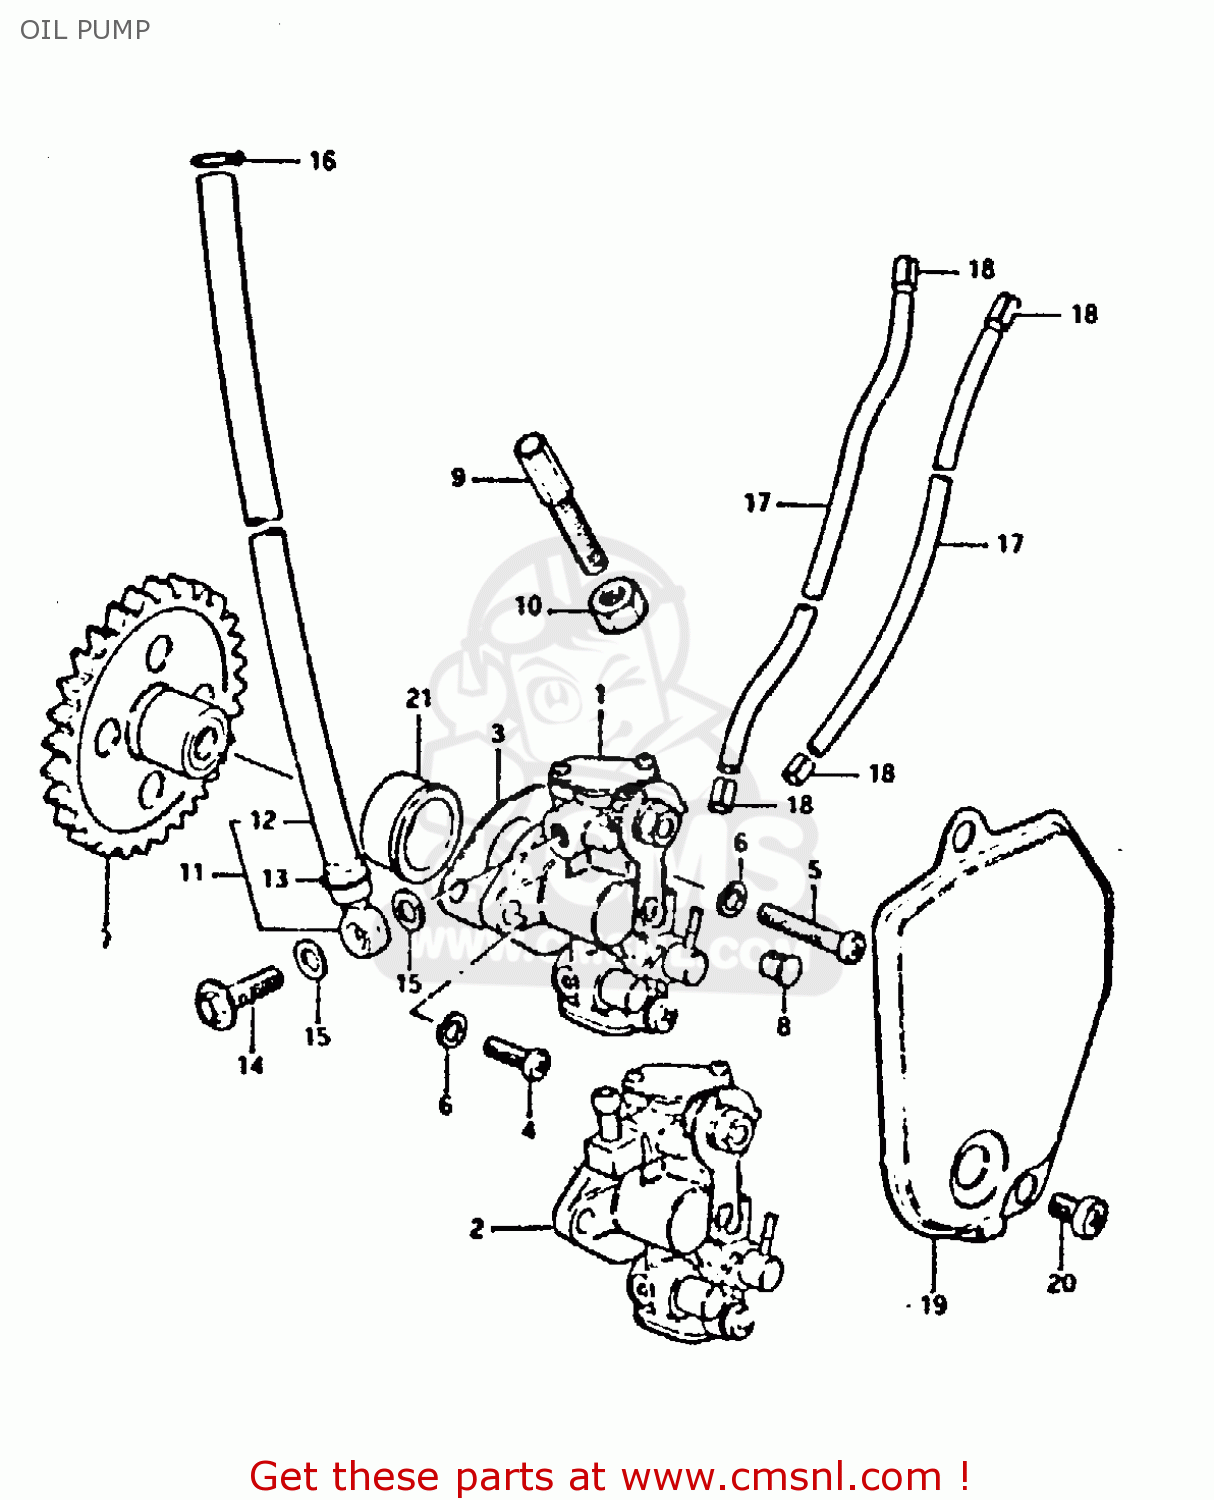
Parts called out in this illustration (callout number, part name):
1	PUMP ASSY, OIL
2	PUMP ASSY, OIL
3	GASKET,OIL PUMP (MCA)
4	SCREW
5	SCREW
6	LOCK WASHER
7	GEAR, OIL PUMP DRIVE
8	TERMINAL,CABLE
9	BOLT
10	NUT
11	HOSE,OIL NO.1
12	HOSE
13	CLIP
14	UNION BOLT
15	GASKET(6.2X11X1).2 (NAS)
16	CLIP
17	HOSE
18	CLIP
19	CAP, INSPECTION
20	SCREW
21	PUSH
